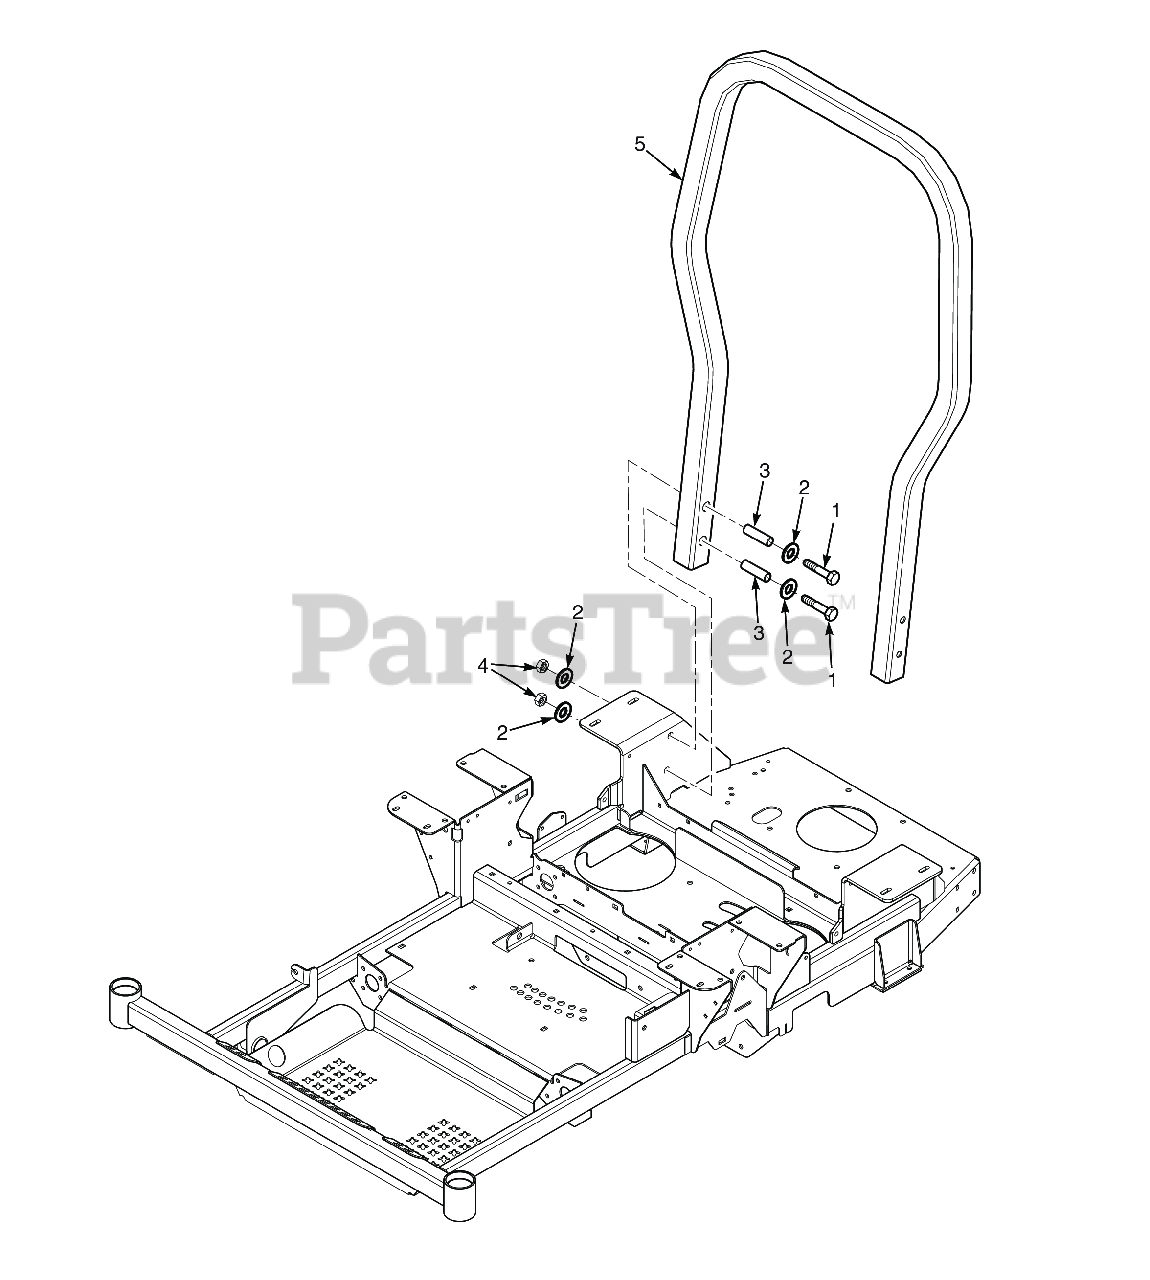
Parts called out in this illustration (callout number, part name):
1	Bolt, Hex Head 1/2-13 x 3-1/4" Gr. 8
2	Flatwasher, 1/2 - .531 x 1.062 x .095
3	Bushing, SFZ ROPS
4	Locknut, Hex 1/2-13 Center Lock
5	ROPS, SFZ48, SFZ52
